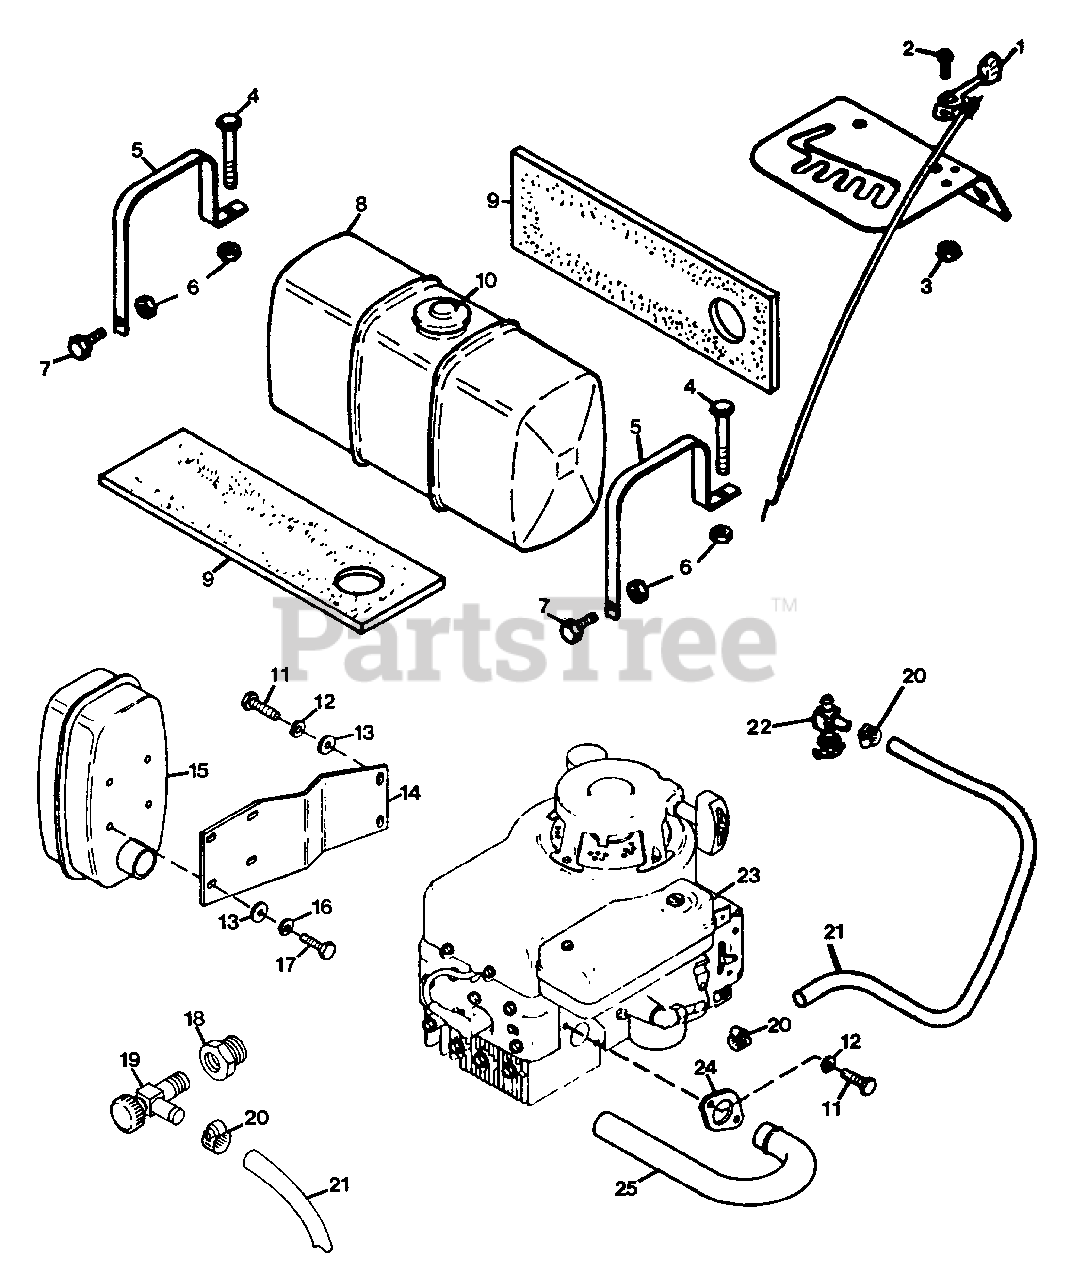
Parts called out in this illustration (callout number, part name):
1	LEVER, CONTROL
2	SCREW, MACH. 10-24X.50 PHD
3	NUT, LOCK 10-24
4	BOLT, HEX 1/4-20X1.75
5	STRAP, FUEL TANK
6	NUT, LOCK 1/4-20
7	BOLT, HEX 1/4-20X.625
8	TANK, FUEL (12 QTS.)
9	PAD, GAS TANK
10	CAP, GAS TANK
11	BOLT, HEX 5/16-18X.75
12	WASHER, LOCK 5/16 REG.
13	WASHER, FLAT .344X.688X.065
14	PLATE, EXHAUST
15	MUFFLER
16	WASHER, LOCK 1/4 REG.
17	BOLT, HEX 1/4-20X.75
18	ADAPTOR, OIL DRAIN
19	COCK, OIL DRAIN
20	CLAMP, HOSE
21	HOSE, FUEL
22	VALVE AND STRAINER
23	ENGINE, 12 H.P. B&S
24	FLANGE, MUFFLER
25	TUBE, EXHAUST
